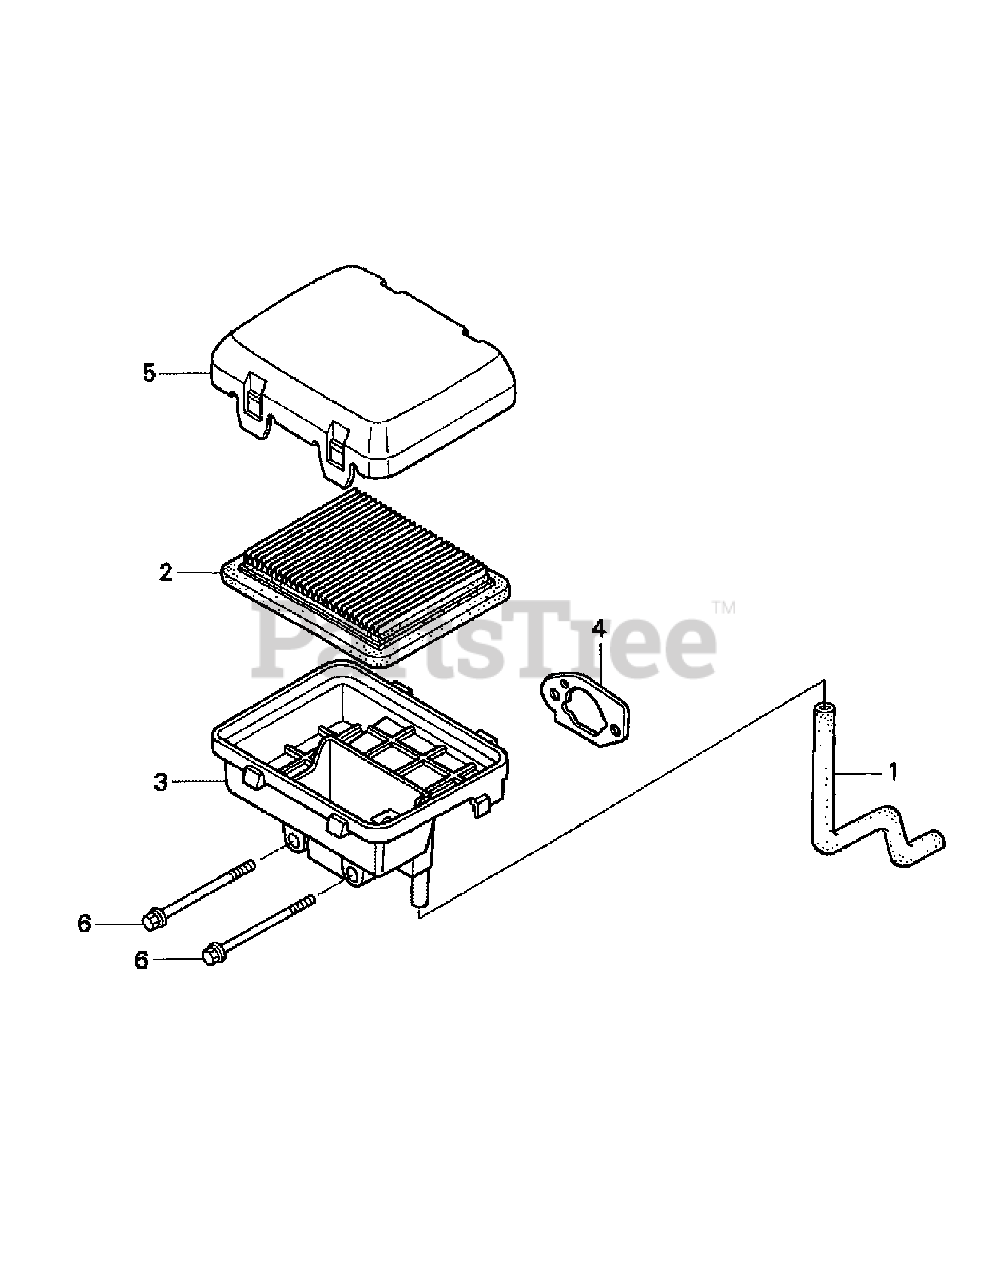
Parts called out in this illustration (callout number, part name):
1	Breather Tube
2	Air Cleaner Element
3	Air Cleaner Housing
4	Air Cleaner Gasket
5	Air Cleaner Cover
6	Flange Bolt, 6 x 112
